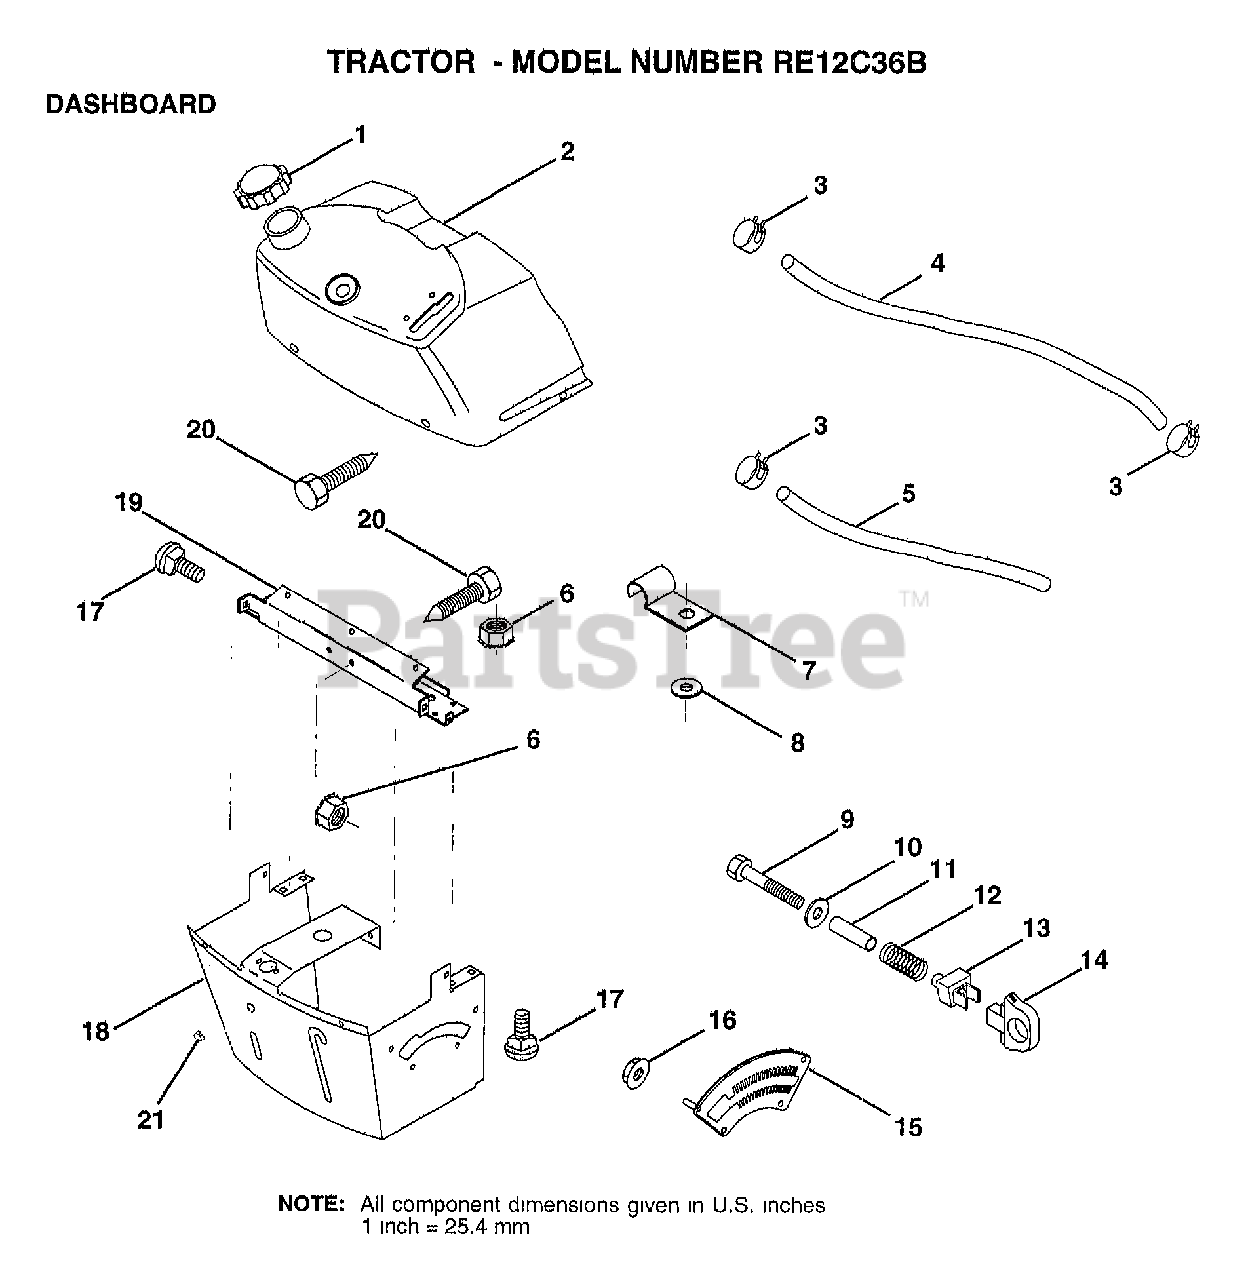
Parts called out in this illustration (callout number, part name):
1	CAP BLK FUEL LR
2	TANK.ASM.DASH.LR
3	HOSE CLAMP
5	FUEL LINE T
6	NUT HXKEP 1/4X20
7	CLIP T
8	WASHER PM
9	BOLT
11	SPACER SPLIT
12	SPRING M
13	"KNOB,HGT RETAINER"
14	KNOB
15	ADJUSTER QUAD
16	NUT
17	BOLT
18	SUPT ASSY DASH
19	CROSS BRACE
20	SCREW.1/4-20X1/2
21	PLUG DOME
